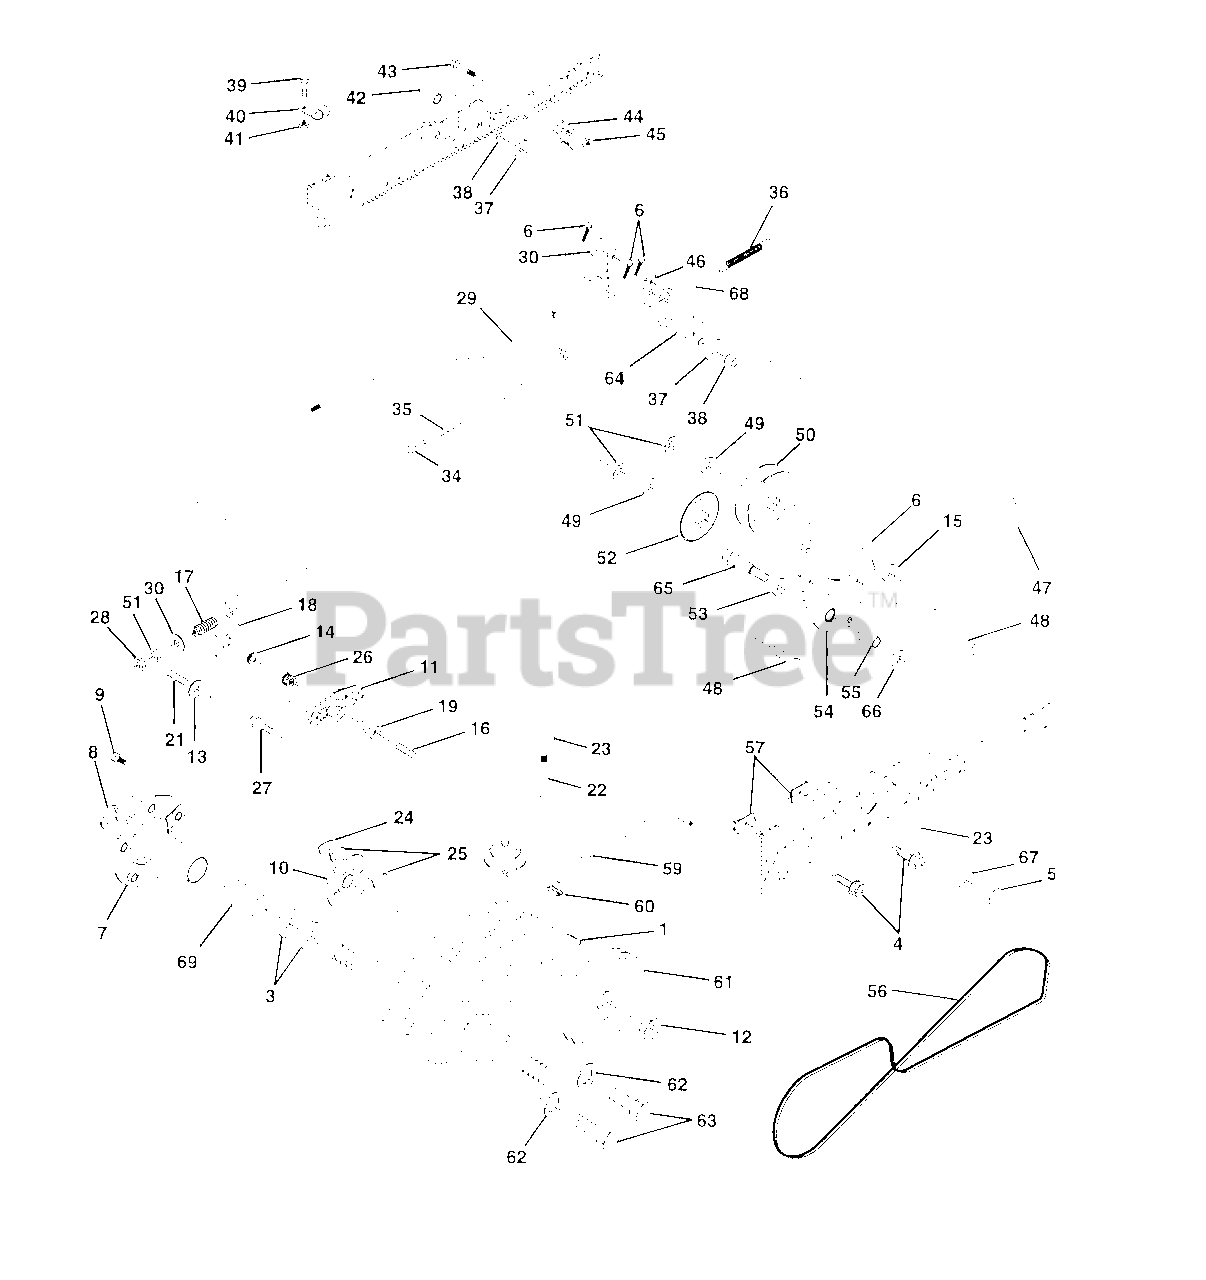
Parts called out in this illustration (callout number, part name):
1	Key Woodruff
3	Washer Thrust Axle Harden
4	Screw Thdrol 5/16-18 x 1/2 TYT
5	Nut Crownlock 3/8-16
6	Pin Cotter 1/8 x 3/4
7	Wheel Hub Asm.
9	Bolt Hub
10	Disc Brake
11	Yoke Brake Disc
12	Locknut 1/2 20
13	Washer Special
15	Washer 13/32 x 13/16 x 16 Ga
16	Set Screw 1/4-28 x 3/4
18	Lever Brake
19	Cam Brake Disc
21	Screw Flat Head 1/4-28 x 3/4
22	Gearshift Lever Assembly
24	Support Puck Brake
25	Puck Brake Top
26	Spring Return
27	Screw Hex Wsh Thd 5/16-18 x 1-3/4
28	Nut Hex Jam 3/8-16
30	Washer 13/32 x 1 x 16 Ga
34	Cap Plunger
35	Rod Parking Brake
36	Spring Drive Ground
37	Washer 25/32 x 1-1/4 x 16 Ga
39	Screw Fin #10-24 x 1
40	Actuator Interlock Switch
41	Nut Lock #10-24
42	Cover Pedal
43	Bolt Hex Head 1/4-20 x 3/4
44	Bracket Interlock
45	Nut Lock W/Insert 1/4-20
46	Retainer Spring
47	Clutch Rod
48	Bolt Carriage 3/8-16 x 1-3/4 Gr 5
49	Washer 13/32 x 7/8 x 13 Ga
50	Pulley Idler Flat
51	Nut Lock Hex 3/8-16
52	Pulley Idler Grooved
53	Washer Hartdened
54	Clutch Arm Asm
55	Bearing, Idler
57	Bracket Shift Rod Hi-Lo
59	Shift Rod Hi-Lo
60	Spring Clip Connecting Link
61	Pulley Transaxle
62	Washer Lock 7/16
63	Bolt Fin Hex 7/16-14 x 1-1/4
64	Shaft Clutch/Brake Pedal
65	Bolt Shoulder
66	Washer Hardened
67	Washer 13/32 x 13/16 x 12 Ga.
